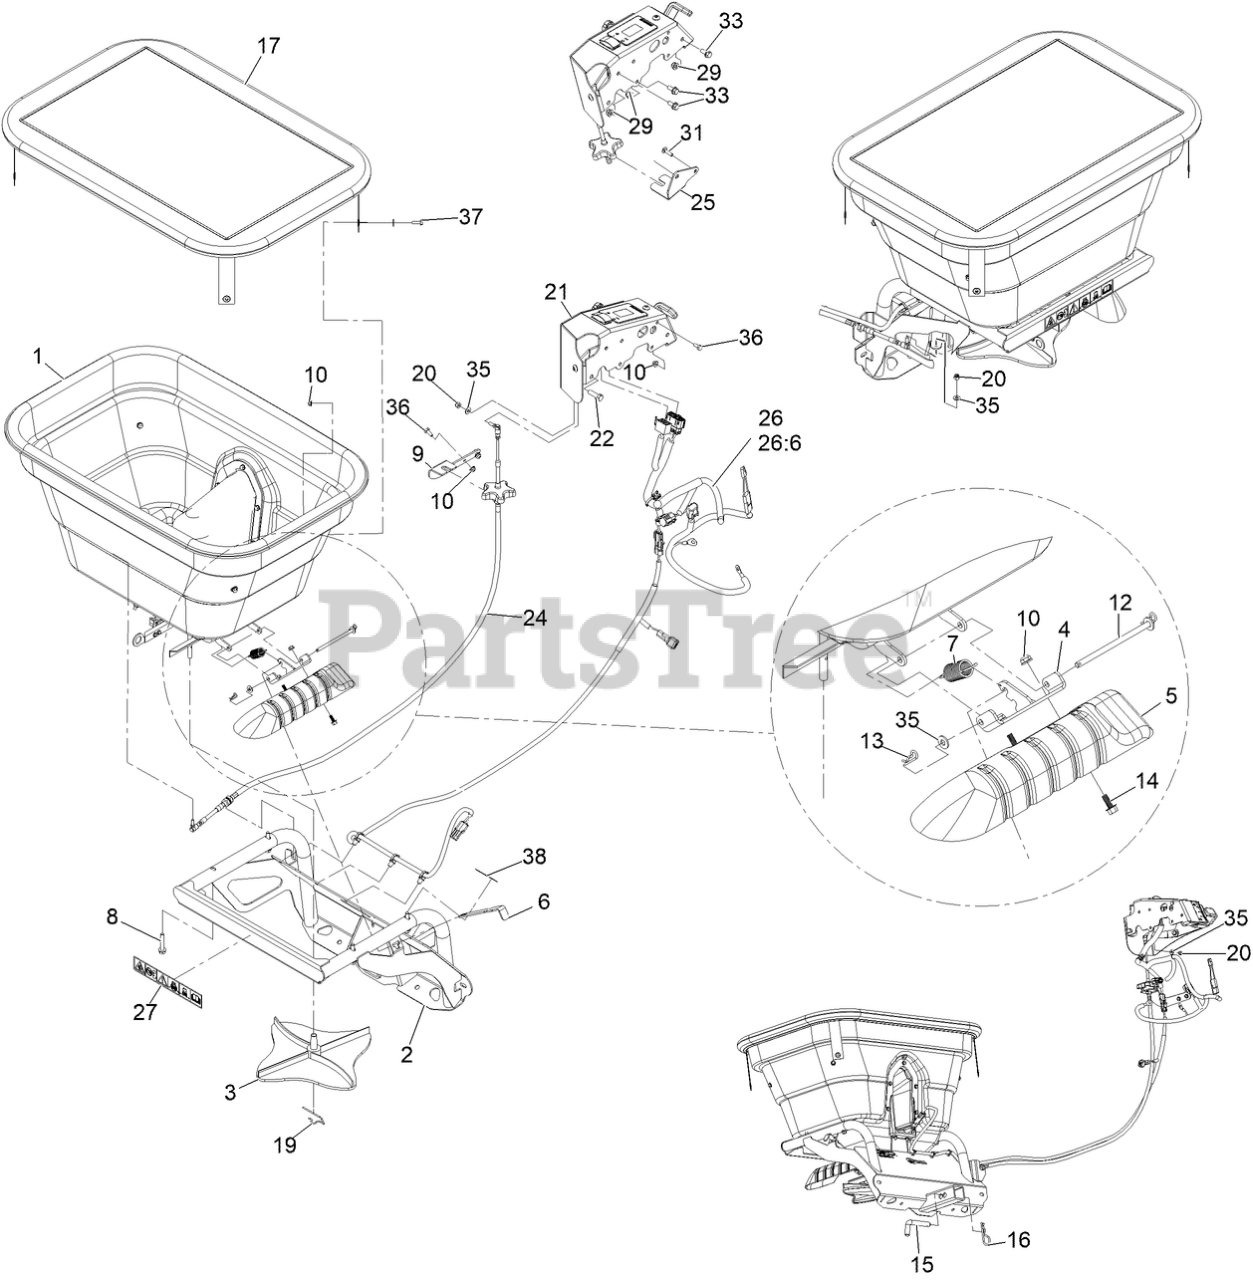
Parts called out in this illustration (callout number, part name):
1	Asy-Spreader Hopper
2	SPREADER HOPPER FRAME ASM
3	SPINNER-SPREADER
4	BRACKET-DEFLECTOR
5	DEFLECTOR
6	STRAP-ENGAGEMENT
7	Spring-Extension
8	Screw-HWH
9	BRACKET-CABLE
12	PIN-PIVOT
13	PIN-COTTER
14	SCREW-HHF
15	PIN-HITCH
16	PIN-HAIR
17	COVER-HOPPER
19	CLIP-SPINNER
20	NUT-LOCK
21	Spreader Controller ASM
22	SCREW-HH
24	CABLE-PUSH, PULL
25	BRACKET-CABLE
26	HARNESS
26:6	CONNECTOR
27	DECAL-DOWN, TIE
29	NUT-HF, NI
31	SCREW-CARR
33	SCREW-HHF
35	WASHER-FLAT
36	SCREW-HH
37	SCREW-HWH
38	DECAL-WARNING
